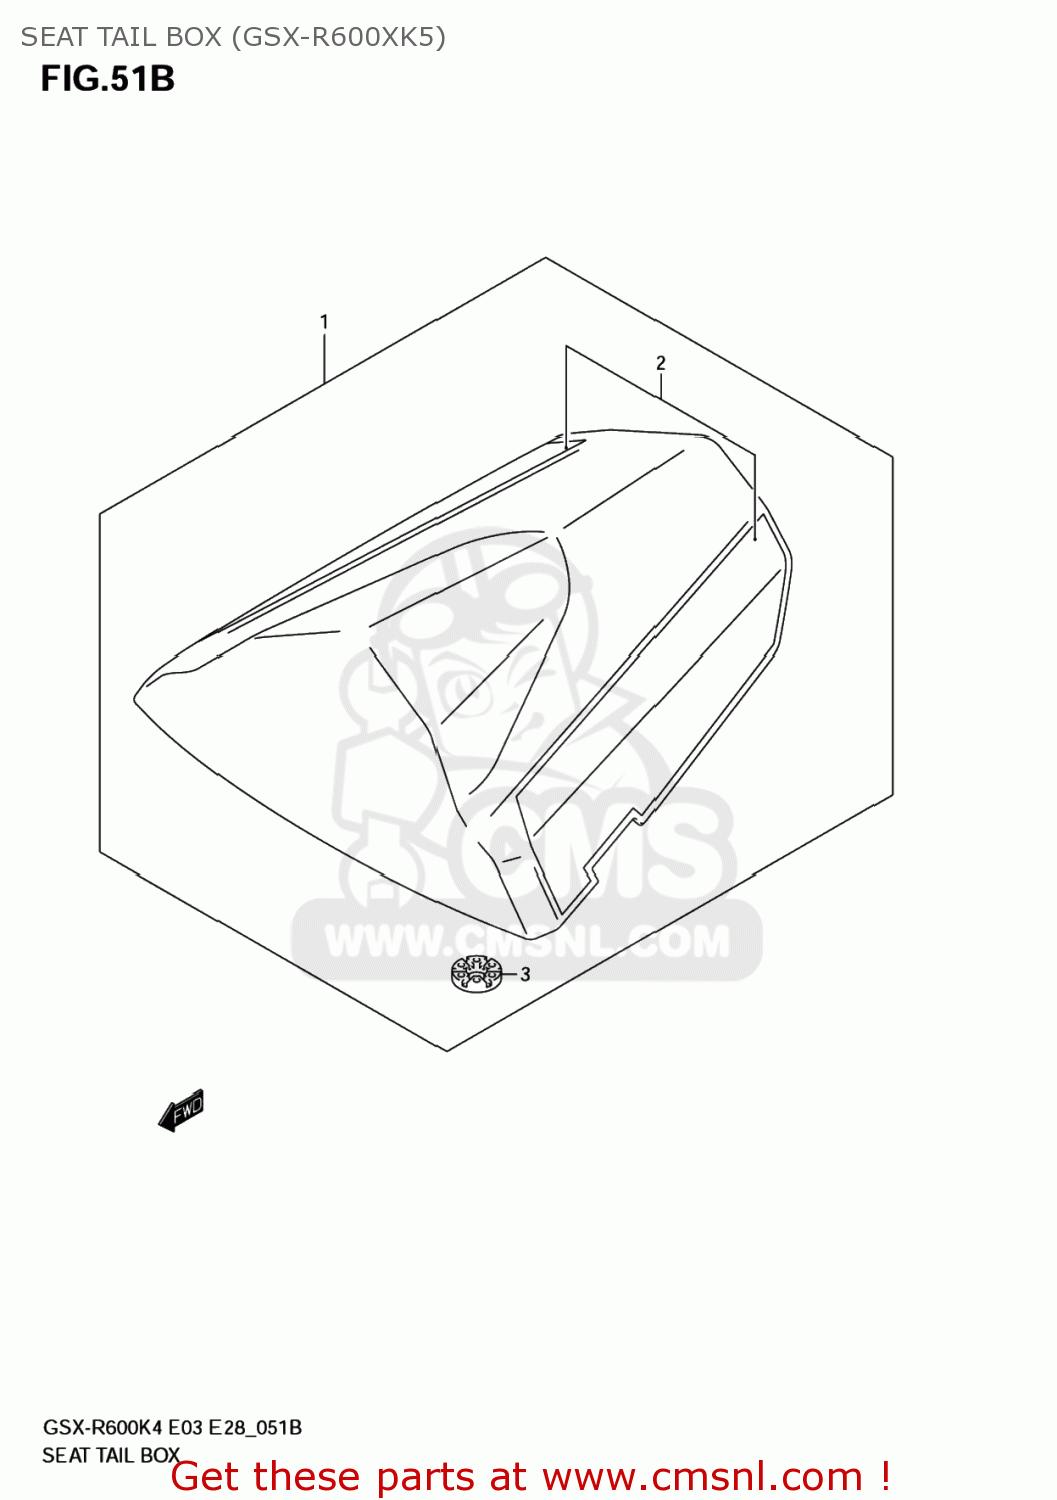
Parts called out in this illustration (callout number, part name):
1	BOX ASSY,SEAT TAIL(BLUE)
2	TAPE SET,BOX SEAT TAIL
3	CUSHION
